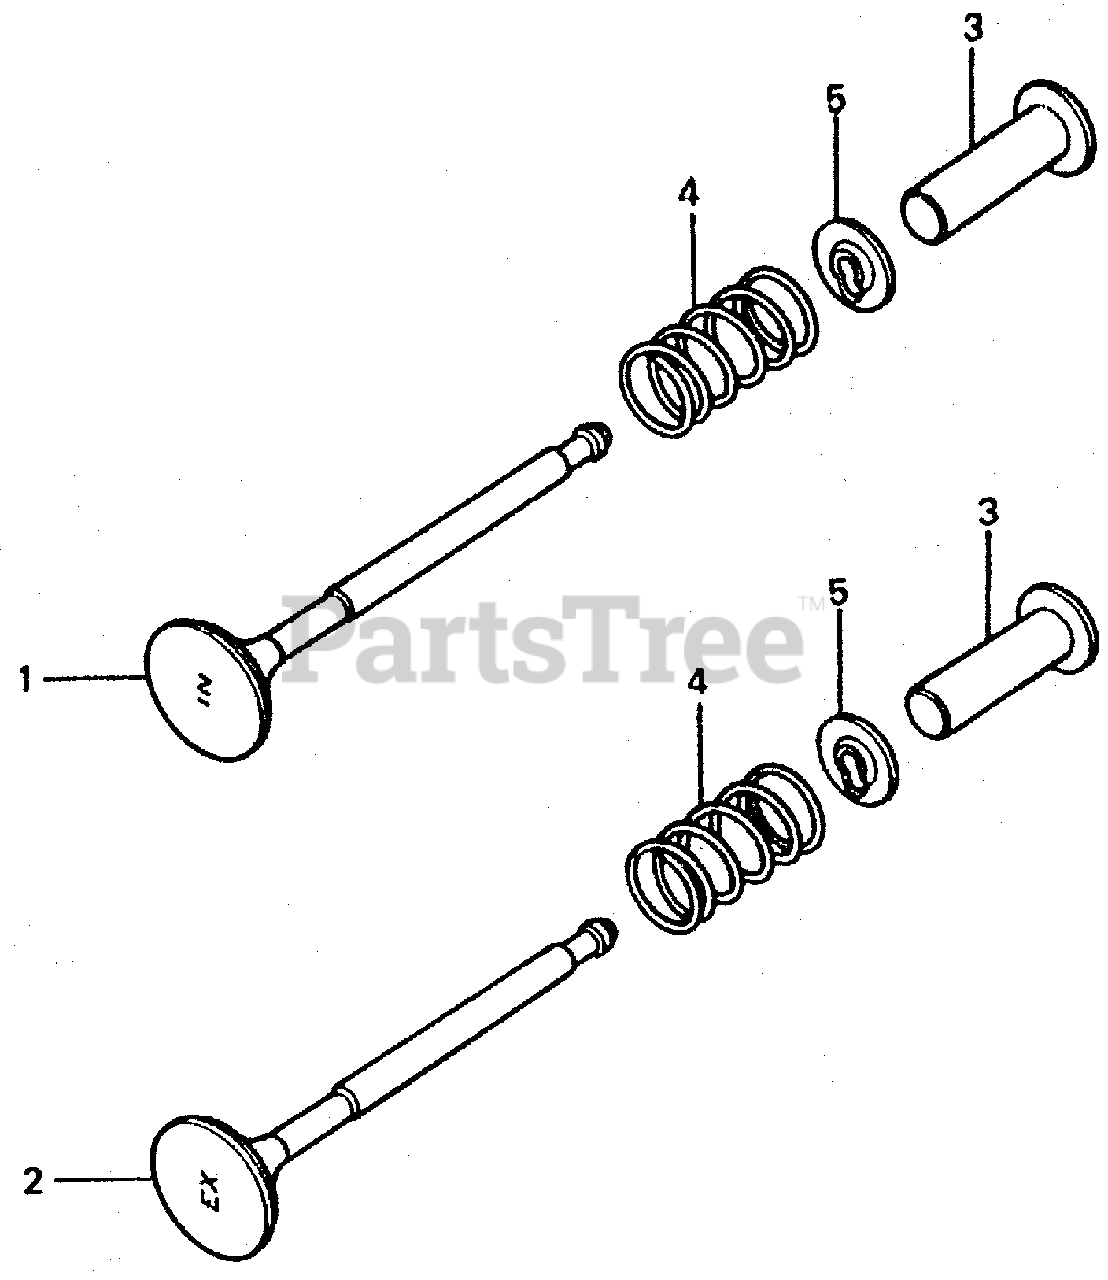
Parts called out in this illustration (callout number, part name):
1	VALVE, IN.
2	VALVE, EX.
3	LIFTER, VALVE (31.33)
3	LIFTER, VALVE (31.51)
3	LIFTER, VALVE (31.66)
4	SPRING, VALVE
5	RETAINER, VALVE SPRING
